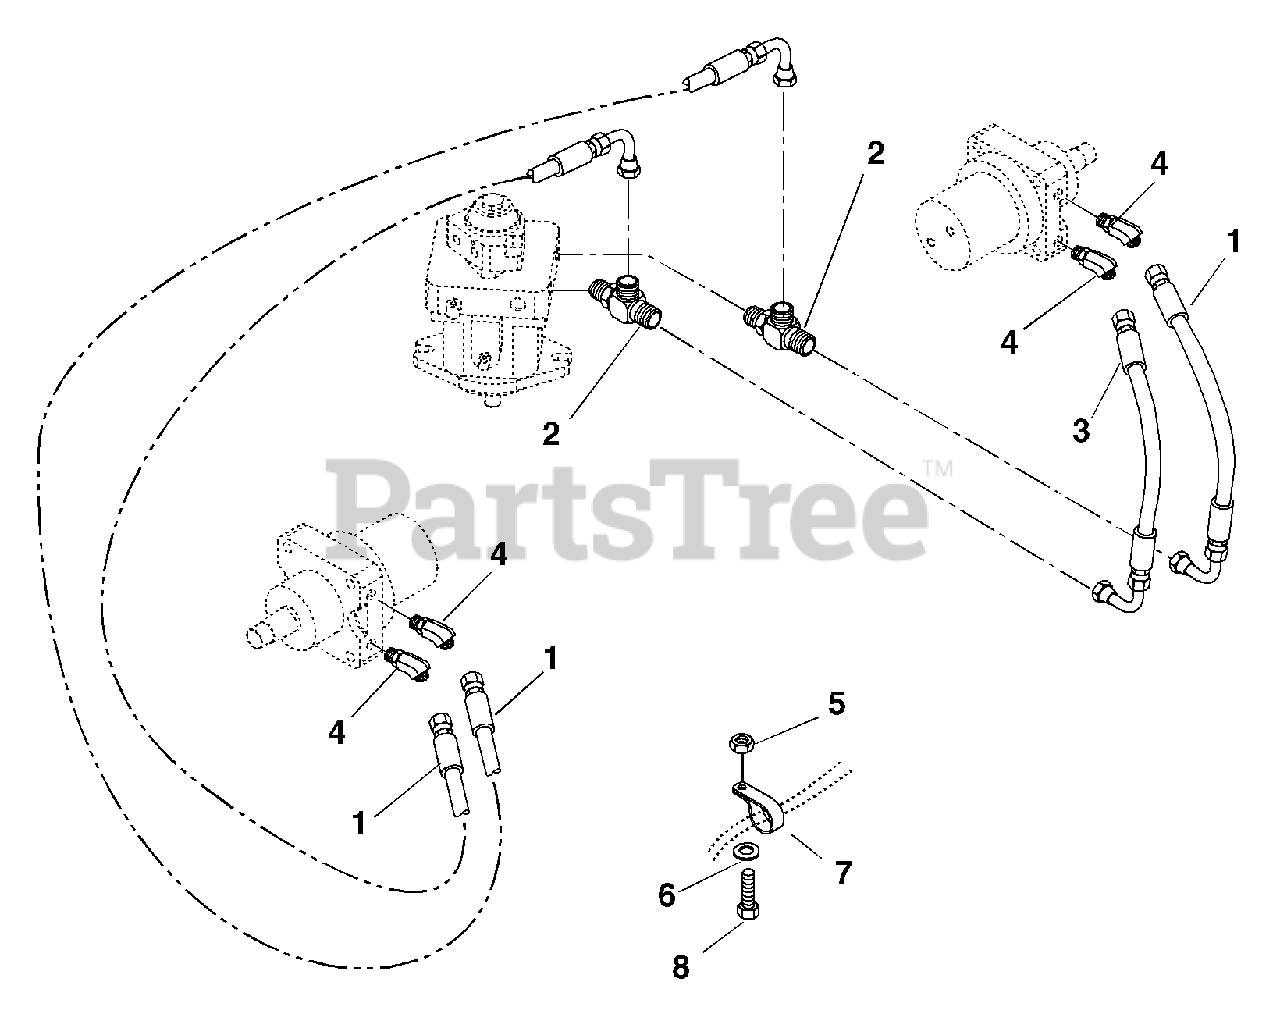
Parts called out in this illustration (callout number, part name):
1	Hose, Pump To Motor
2	Fitting, Hydraulic
3	Hose, Pump To Motor
4	Fitting, Hydraulic
5	Nut-Locking-Nylon .38-16
6	Washer-Flat-Steel .406 x .812 x .065
7	Clamp, Nylon
8	Bolt-Hex .38-16 x 1.00 Grade 5
